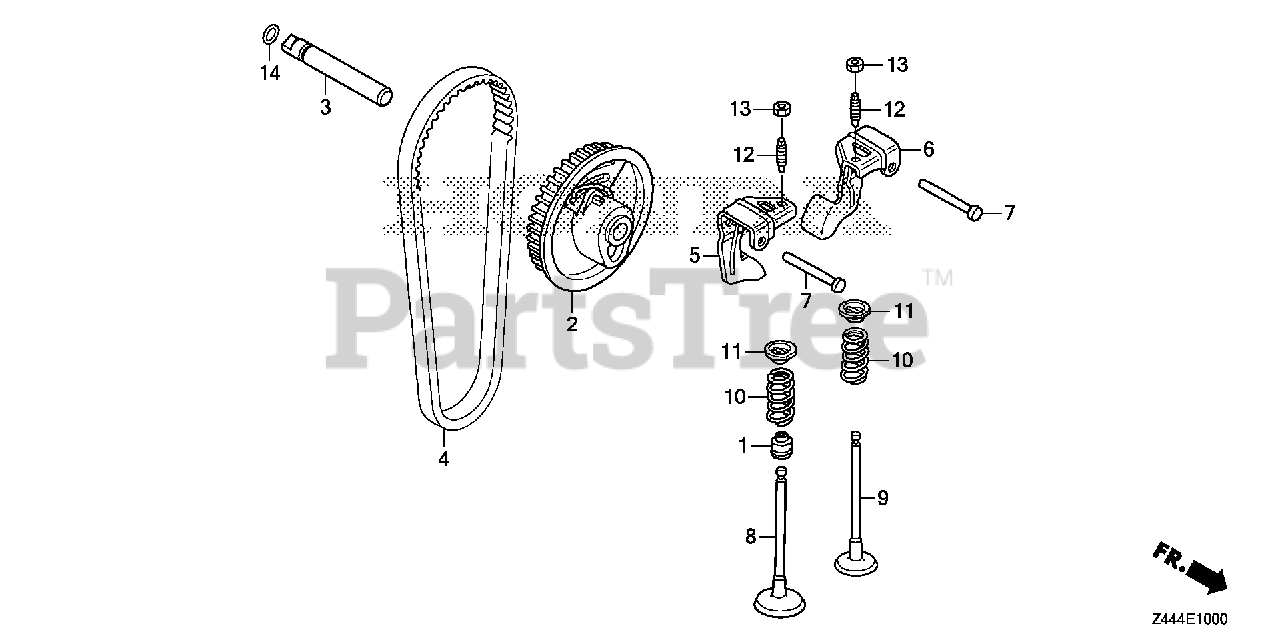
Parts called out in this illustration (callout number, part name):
1	SEAL, VALVE STEM
2	PULLEY, CAMSHAFT
3	SHAFT, CAM PULLEY
4	BELT, TIMING (61YU7 G-200)
5	ARM, IN. VALVE ROCKER
6	ARM, EX. VALVE ROCKER
7	SHAFT, ROCKER ARM
8	VALVE, IN.
9	VALVE, EX.
10	SPRING, VALVE
11	RETAINER, VALVE SPRING
12	SCREW, TAPPET ADJ.
13	NUT, TAPPET ADJ.
14	O-RING (6.8X1.9) (ARAI)
